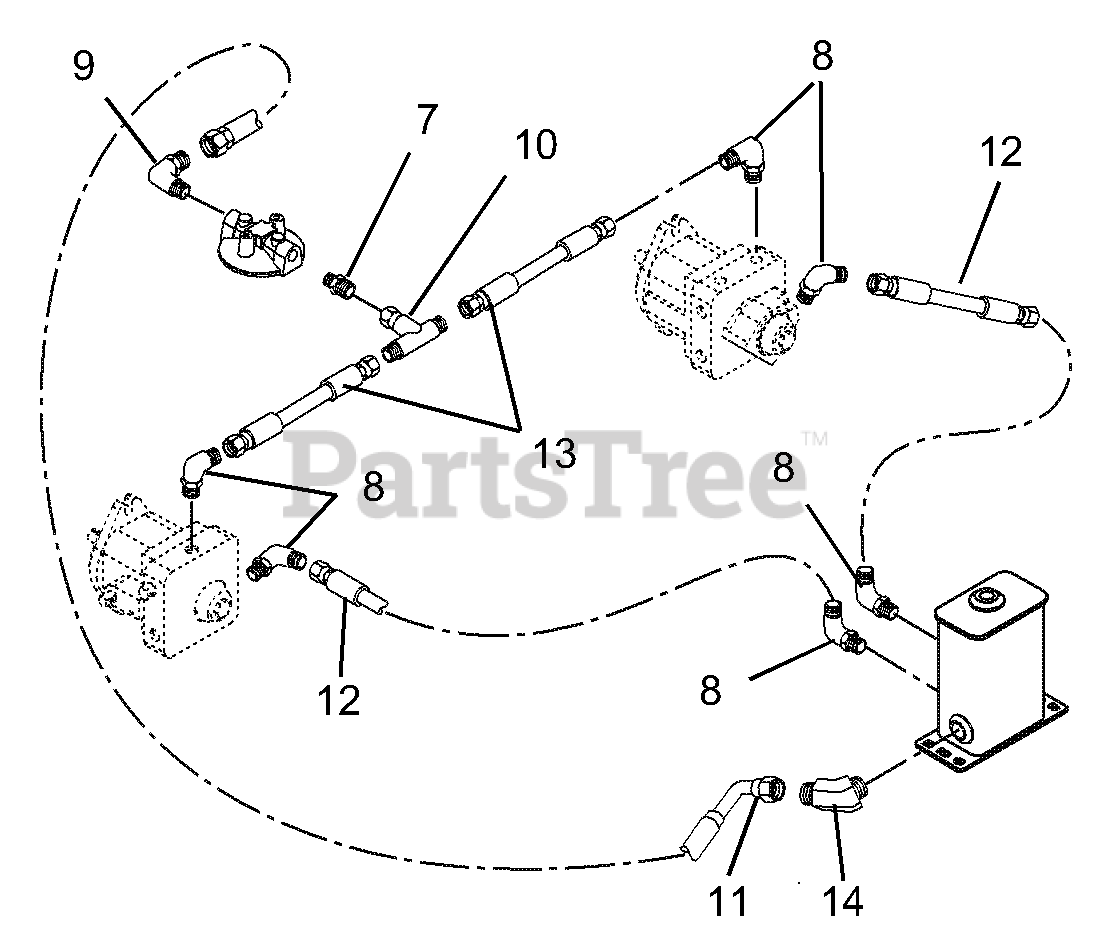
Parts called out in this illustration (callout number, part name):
7	Straight Fitting (M80-M120)
8	90 Degree Fitting (MF-M80)
9	90 Degree Fitting (M80-M120)
10	Tee Fitting (M80-F80-F80)
11	Hydraulic Hose (0.50-19-0KFO8J0-FO8J9)
12	Hydraulic Hose (0.50-10-0KFO8J0-FO8J0)
13	Hydraulic Hose (0.50-5-0KFO8J0-FO8J0)
14	45 Degree Fitting (M8F-M80)
